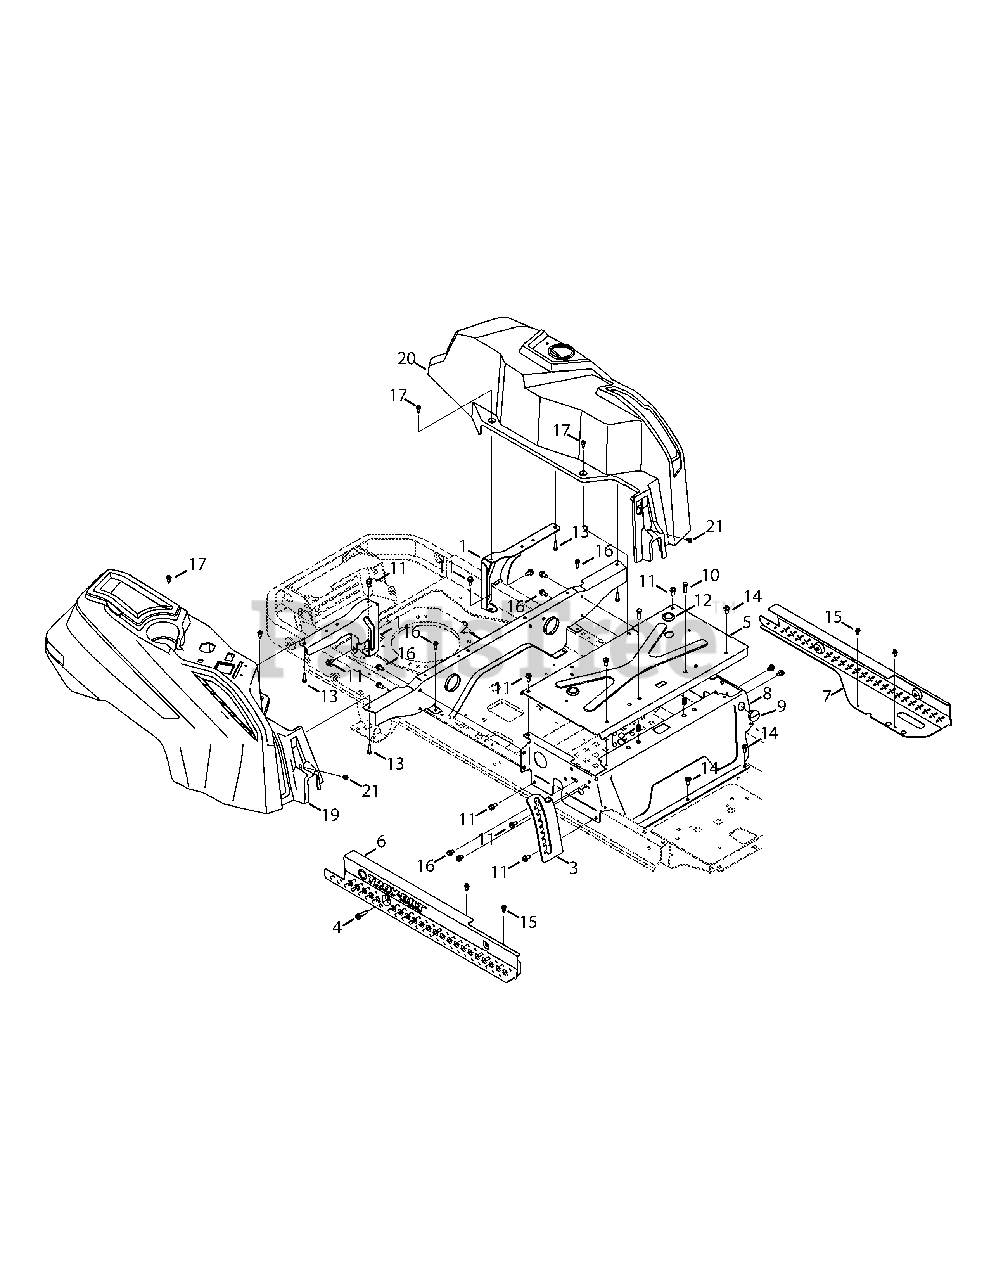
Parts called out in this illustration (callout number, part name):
1	Rear Tank Bracket
2	Rear Seatbox Brace
3	Height Index Bracket
4	Hex Washer Screw, 3/8-16 x 1.25
5	Seatbox Plate
6	Frame Support, RH
7	Frame Support, LH
9	Plastic Plug
10	Hex Cap Screw, 5/16-18 x 1.00
11	Hex Washer Screw, 5/16-18 x .750
12	Button Plug
13	Hex Washer Screw, 5/16-14 x 1.00
14	Self Tapping Screw, 5/16-18 x .750
15	Hex Washer Screw, 1/4-20 x .500
16	Hex Washer Screw, 5/16-18 x .50
17	Shoulder Screw, .368 x .115, M6-1
18	Nut, 5/16-18
19	RH Console
20	LH Console
21	Shoulder Screw, 1/4-20
